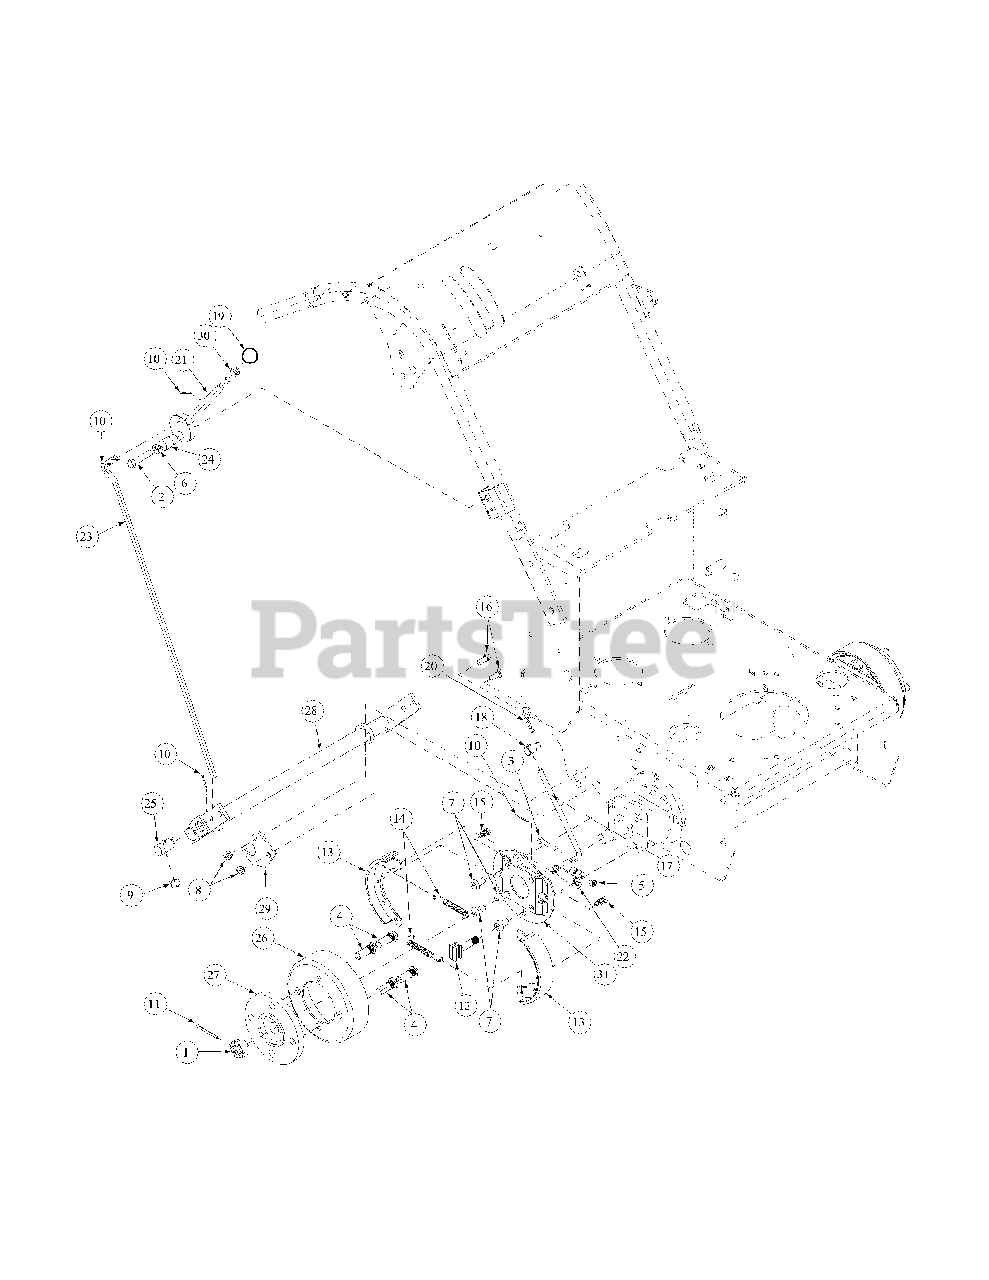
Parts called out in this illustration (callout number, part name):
1	Nut, Castle, 3/4-16
2	Capscrew, 3/8-16 x 1-3/4" Zinc
3	Cap Screw, 1/4-20 x 1.50, Grade 5
4	Bolt, Wheel, 1/2-20 x 1-3/8
5	Lock Nut, Nylon Insert, 1/4-20 Grade
6	Lock Washer, 3/8 Zinc
7	Capscrew, Socket Button Hd., 3/8-16 x 3/4 Zinc
8	Nut, 5/16-18, Nylock
9	Nut, Nylon Insert, 3/8-16 Grade A
10	Cotter Pin, 3/32 x 3/4, Zinc
11	Cotter Pin, 5/32 x 1-1/2 Zinc
12	Brake Cam, Actuating
13	Brake Shoe w/Lining, 6 x 1-1/4
14	Brake Spring, Tension
15	Brake Spring, Anti-Vibration
16	Cap Screw, 5/16-18 x 3/4, Grade 5
17	Brake Rod
18	Swivel Joint
19	Red Knob, Shift w/Insert
20	Hair Pin 3/8"-1/2"
21	Lever Assembly, Brake
22	Brake Clamp, Control Assembly Hydro
23	Rod, Long Brake, Hydro WB
24	Pivot Spacer, Hydro WB
25	Brake Pull Joint
27	Hub, Wheel Motor
28	Brake Pivot Shaft Assembly
29	Pivot Mount, Brake
30	Nut, 3/8-16, Jam, Grade 2
31	Brake Backing Plate
